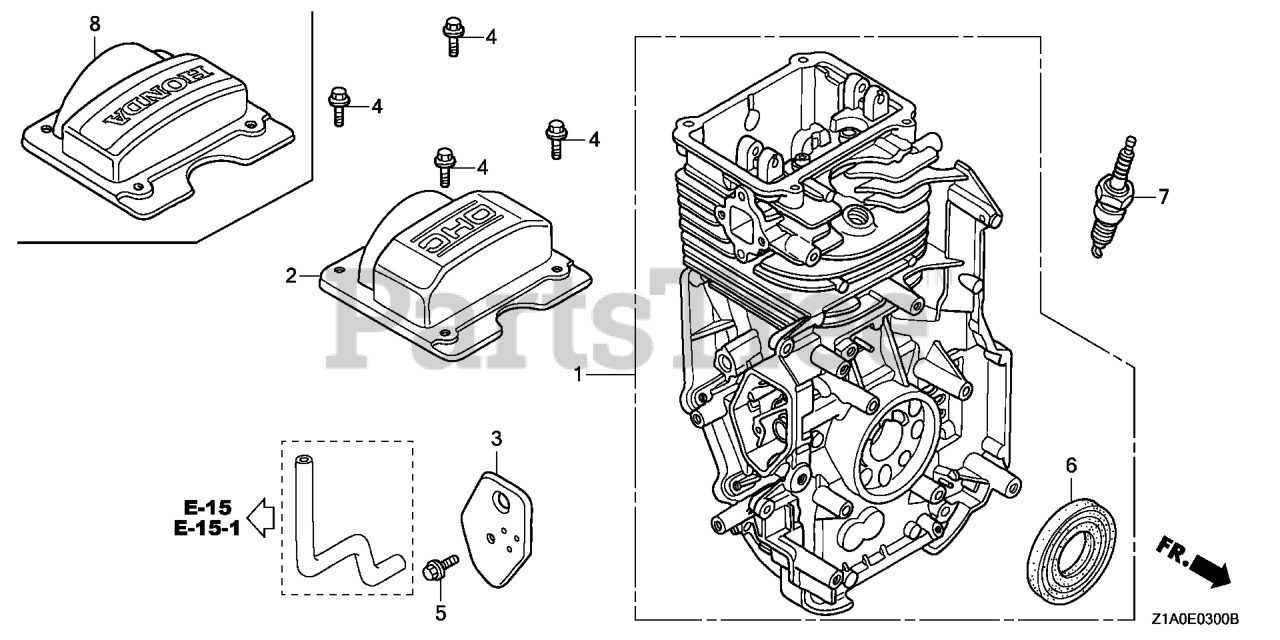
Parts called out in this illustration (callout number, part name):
1	CYLINDER ASSY.
2	COVER, CYLINDER HEAD
3	COVER, BREATHER (Honda Code 5580006). (BREATHER VALVE ASSY.)
4	BOLT, FLANGE (6X12) (CT200)
5	BOLT, FLANGE (6X14)
6	OIL SEAL (25.4X62X6)
7	SPARK PLUG (BPR6ES) (NGK)
